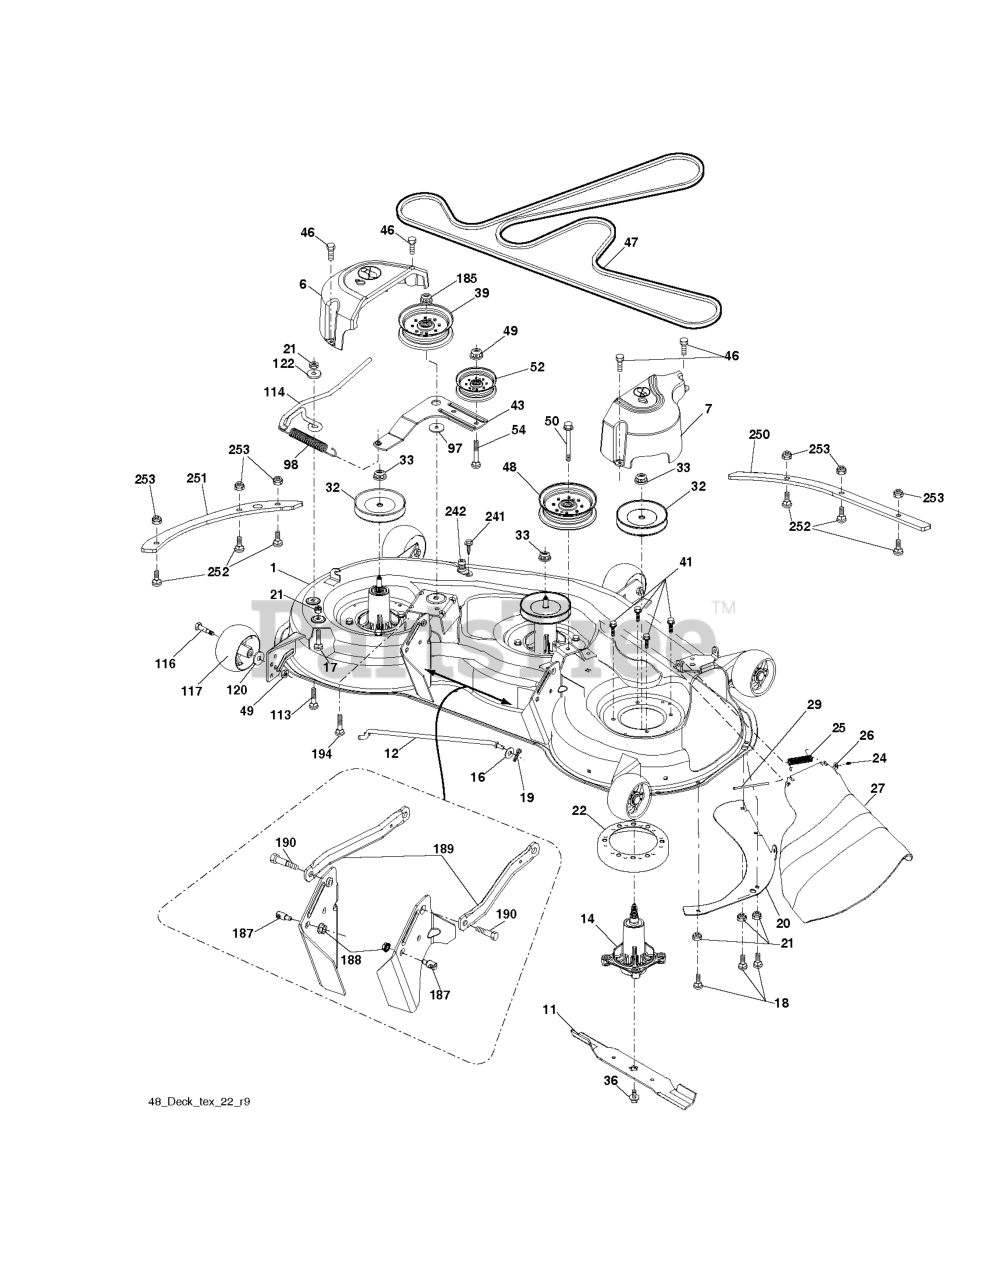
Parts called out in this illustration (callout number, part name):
1	DECK.SVC 48".4GWB.O
6	COVER.MANDREL.LH.48"(2 2)
7	COVER.RH.MANDREL
11	48" HI-LIFT BLADE
12	ROD.ANTI.SWAY.48/54"K4
14	KIT.MANDREL.GREASEABLE.TALL
17	BOLT.CARR.5/16-18X5/8.SHORT
19	PIN.COTTER.5/16.BOW TI
20	BAFFLE, VORTEX MWR
22	STRIPPER.MANDREL.ROUND.BLACK
24	CAP-SLEEVE LT
25	SPRING, TORSION
26	NUT PUSH M
27	DEFLECTOR SUBS TO 532 180655
32	PULLEY MANDREL
36	SCREW.SEMS.7/16-20X1.HEX.HEAD
39	RB PULLEY.IDLER.4.50/HUB SPEC
41	BOLT.HEX.WASHR.HED.313-18X1.19
46	SCREW.1/4-20X5/8
47	Belts- 197242
48	PULLEY.IDLER.2006
49	NUT LOCK FLG 3/8-16 UNC
50	SCREW TT 3/8-16X2.31 UNC
50	SCREW TT 3/8-16X2-1/4 UNC
52	PULLEY.IDLER.48"PRIMARY
54	GSPW Bolts
98	SPRING, DECK DRIVE
113	RHSSNB 5/16C X 1.0
114	ROD.TENSION.RELIEF.TEX (2 2)
117	WHEEL.GAUGE.RALLY
122	BUSHING.RELIEF.TENSION
185	NUT.LOCK.FLANGE.7/16
187	STUD.W/"D"ANTI-ROTATION
188	NUT LOCK HEX FLANGE 5/16-18
189	ARM.RFIXED.MOWER.SUSPNSIONX431
190	BOLT.SHOULDER
194	BOLT.HEX.WASHER.HEAD.7/16-24X
241	SCREW.TT.#10-32X.5.3/8.FLANGE
242	PORT.WASHOUT
250	PLATE.REIN.FRNT.BOLTON.48X431
251	PLATE.REIN.SIDE.BOLT.ON.48X431
252	BOLT CUP HEAD SQUARE NECK 1/4-
253	NUT T
